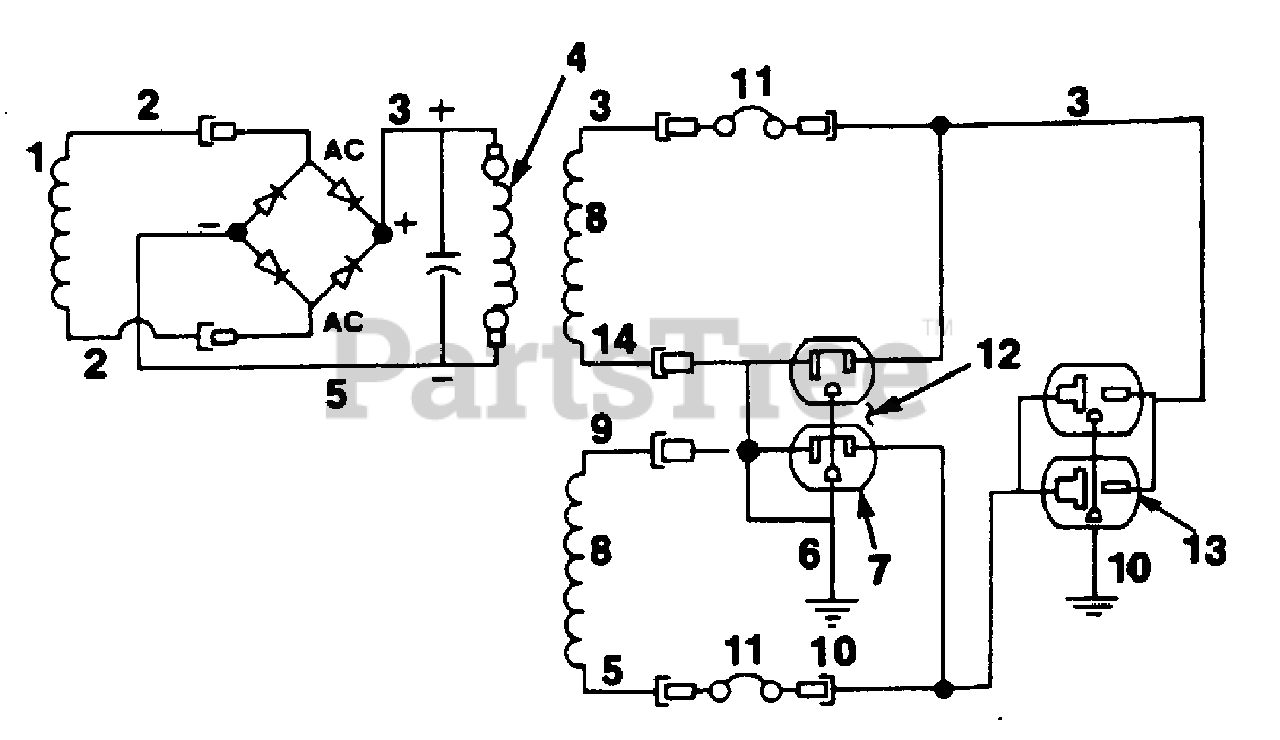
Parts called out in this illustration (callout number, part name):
1	QUAD COIL
2	YELLOW
3	RED
4	FIELD COIL
5	BLACK
6	GREEN
9	WHITE
10	GROUND
11	CIRCUIT BREAKER
12	TAB BROKEN
14	BROWN
